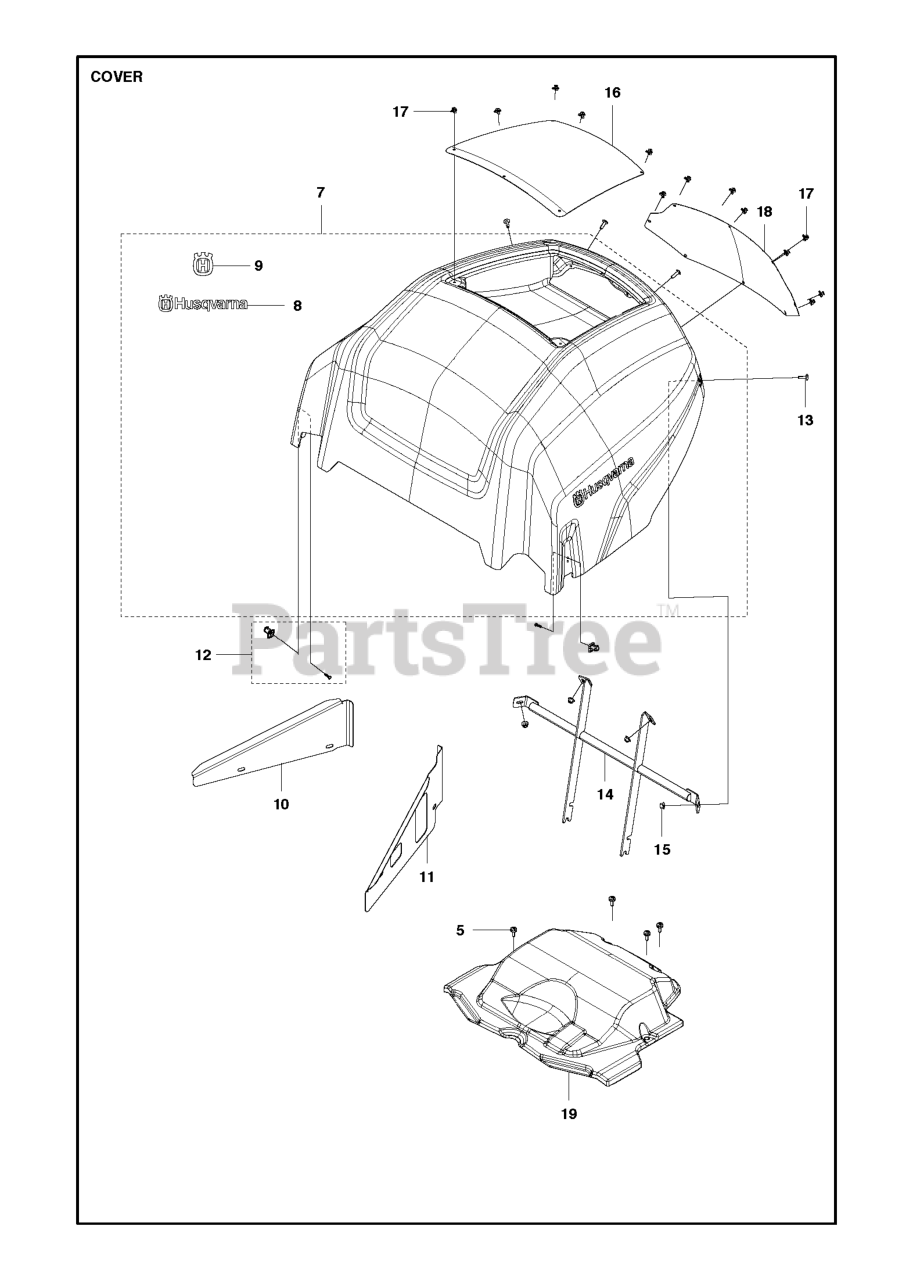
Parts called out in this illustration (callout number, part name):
8	DECAL.HUSQVARNA.210MM
9	DECAL HUSQVARNA CROWN HEIGHT 5
15	NUT FLANGE
